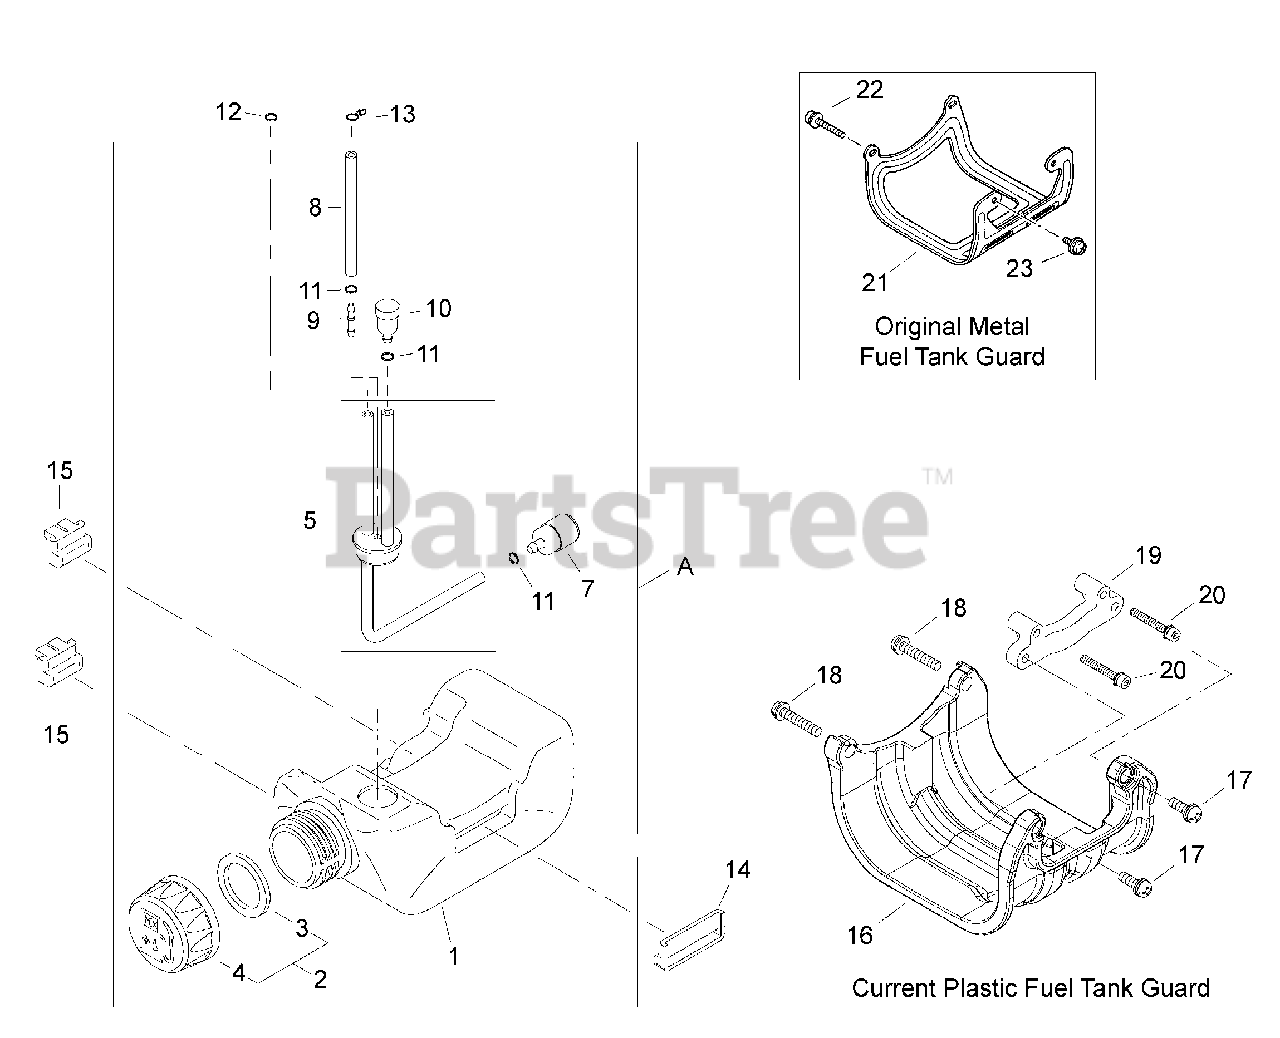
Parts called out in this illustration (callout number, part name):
1	TANK, FUEL
2	CAP ASSY
3	GASKET, CAP
4	CAP, FUEL
5	FUEL PIPE ASSY
7	FILTER, FUEL
8	PIPE - RETURN
8-A	FUEL TANK ASSY
9	CONNECTOR, PIPE
10	VENT, FUEL TANK
11	RING, RETAINING - 6
12	RING, RETAINING - 6
13	CLIP - SPRING
14	CUSHION, FUEL TANK
15	CUSHION, FUEL TANK
16	GUARD, FUEL TANK
17	SCREW - 5X18
18	SCREW - 5X35
19	BRACKET
20	SCREW - 4X30
21	GUARD, FUEL TANK
22	SCREW - 5X30
23	SCREW - 5X12
